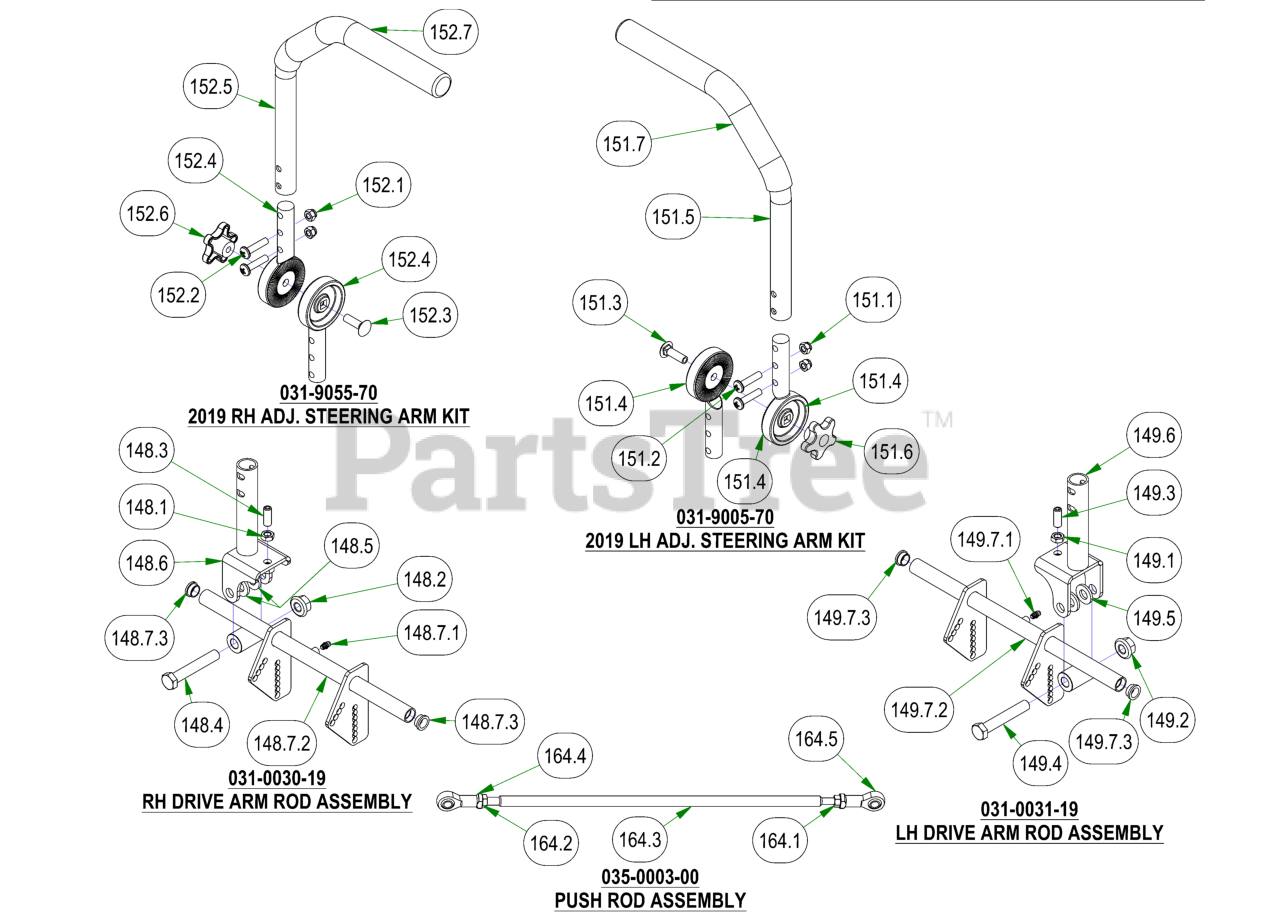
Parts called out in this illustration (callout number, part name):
148	2019 R Series RH Arm Rod Assembly
148.1	3/8-16 Half Jam Nut
148.2	1/2-13 NYLON INSERT FLANGE LOCKNUT ZINC
148.3	3/8-16 X 1 SOCKET SET SCREW (CUP POINT) PLAIN
148.4	1/2-13 X 3 HEX CAP SCREW (GR.5) ZINC
148.5	.505 ID X 1.000 OD X .125 THICK FLAT WASHER NYLON
148.6	Drive Arm Pivot
148.7	2019 Drive Arm Actuator right
148.7.1	1/4" Press in Grease Fitting
148.7.2	2019 Drive Arm Actuator right - Weldment
148.7.3	2019 Drive Arm Bushing
149	2019 R Series LH Arm Rod Assembly
149.1	3/8-16 Half Jam Nut
149.2	1/2-13 NYLON INSERT FLANGE LOCKNUT ZINC
149.3	3/8-16 X 1 SOCKET SET SCREW (CUP POINT) PLAIN
149.4	1/2-13 X 3 HEX CAP SCREW (GR.5) ZINC
149.5	.505 ID X 1.000 OD X .125 THICK FLAT WASHER NYLON
149.6	Drive Arm Pivot
149.7	2019 Drive Arm Actuator left
149.7.1	1/4" Press in Grease Fitting
149.7.2	2019 Drive Arm Actuator left - Weldment
149.7.3	2019 Drive Arm Bushing
151	2019 Left Hand ADJ. Steering Arm Kit
151.1	5/16-18 NYL INS L/N ZC
151.2	5/16-18 x 1 3/8" Futton Head Torx Drive Bolt
151.3	3/8-16 X 1-1/4 CARRIAGE BOLT ZINC
151.4	2019 Steering Arm Adjuster Casting
151.5	2019 Steering Arm Tube
151.6	Black Knob for Adjustable Steering Arm
151.7	Black Steering Arm Grip
152	2019 Right Hand ADJ. Steering Arm Kit
152.1	5/16-18 NYL INS L/N ZC
152.2	5/16-18 x 1 3/8" Futton Head Torx Drive Bolt
152.3	3/8-16 X 1-1/4 CARRIAGE BOLT ZINC
152.4	2019 Steering Arm Adjuster Casting
152.5	2019 Steering Arm Tube
152.6	Black Knob for Adjustable Steering Arm
152.7	Black Steering Arm Grip
164	2019 Rebel Push Rod Assembly
164.1	5/16 LH Nut
164.2	3/8-24 HEX NUT ZINC YELLOW
164.3	2019 Rebel Push Rod
164.4	Spherical Rod End - Outlaw
164.5	Spherical Rod End - Outlaw
